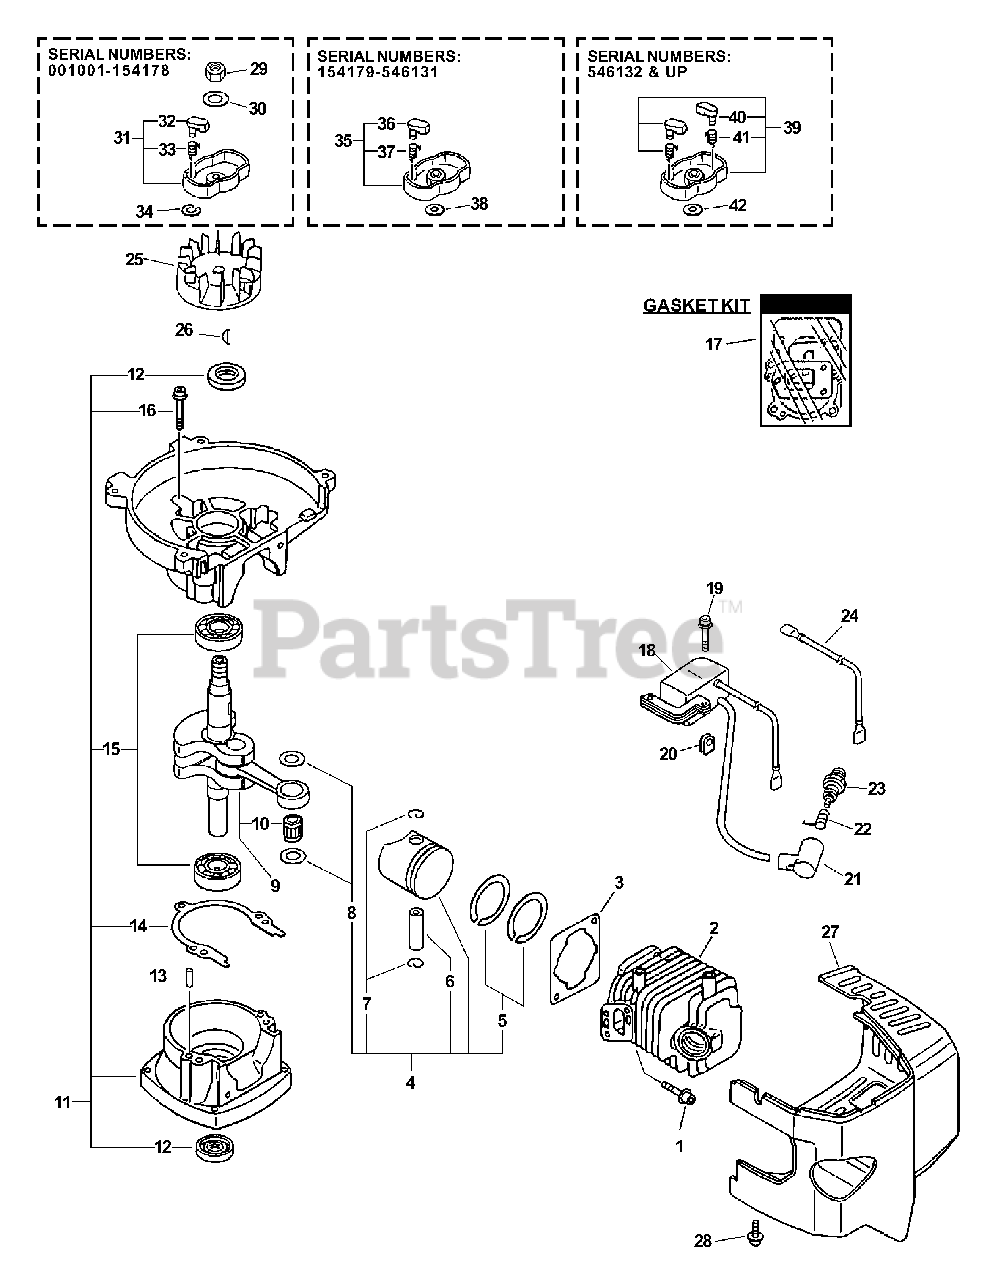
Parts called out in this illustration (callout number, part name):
1	BOLT 5×22
2	CYLINDER
3	GASKET, CYLINDER
4	PISTON KIT
5	RING, PISTON
6	PIN, PISTON 8
7	RING, SNAP
8	WASHER, THRUST
9	CRANKSHAFT ASSY
10	BEARING, NEEDLE 8
11	CRANKCASE KIT
12	SEAL, OIL 12
13	PIN, LOCATING 4
14	GASKET, CRANKCASE
15	BEARING, BALL - 6201 C3
16	BOLT 5×28
17	GASKET KIT
18	COIL, IGNITION
19	SCREW 4×22
21	CAP, SPARK PLUG
22	TERMINAL, SPARK PLUG
23	SPARK PLUG - BPMR7A
24	LEAD
25	FLYWHEEL
27	COVER, ENGINE
27	COVER, CYLINDER
28	SCREW 4×18
29	NUT 8×1.25
30	WASHER 8.5×16×1.2
31	STARTER PAWL ASSY
32	PAWL, STARTER
33	SPRING, RETURN
34	E-RING 4
35	PAWL ASSY, STARTER
36	PAWL, STARTER - BLACK
37	SPRING, RETURN
38	WASHER, SPRING 8
39	PAWL ASSY, STARTER
40	SPRING, RETURN
41	PAWL, STARTER - BLACK
42	WASHER, SPRING 8
